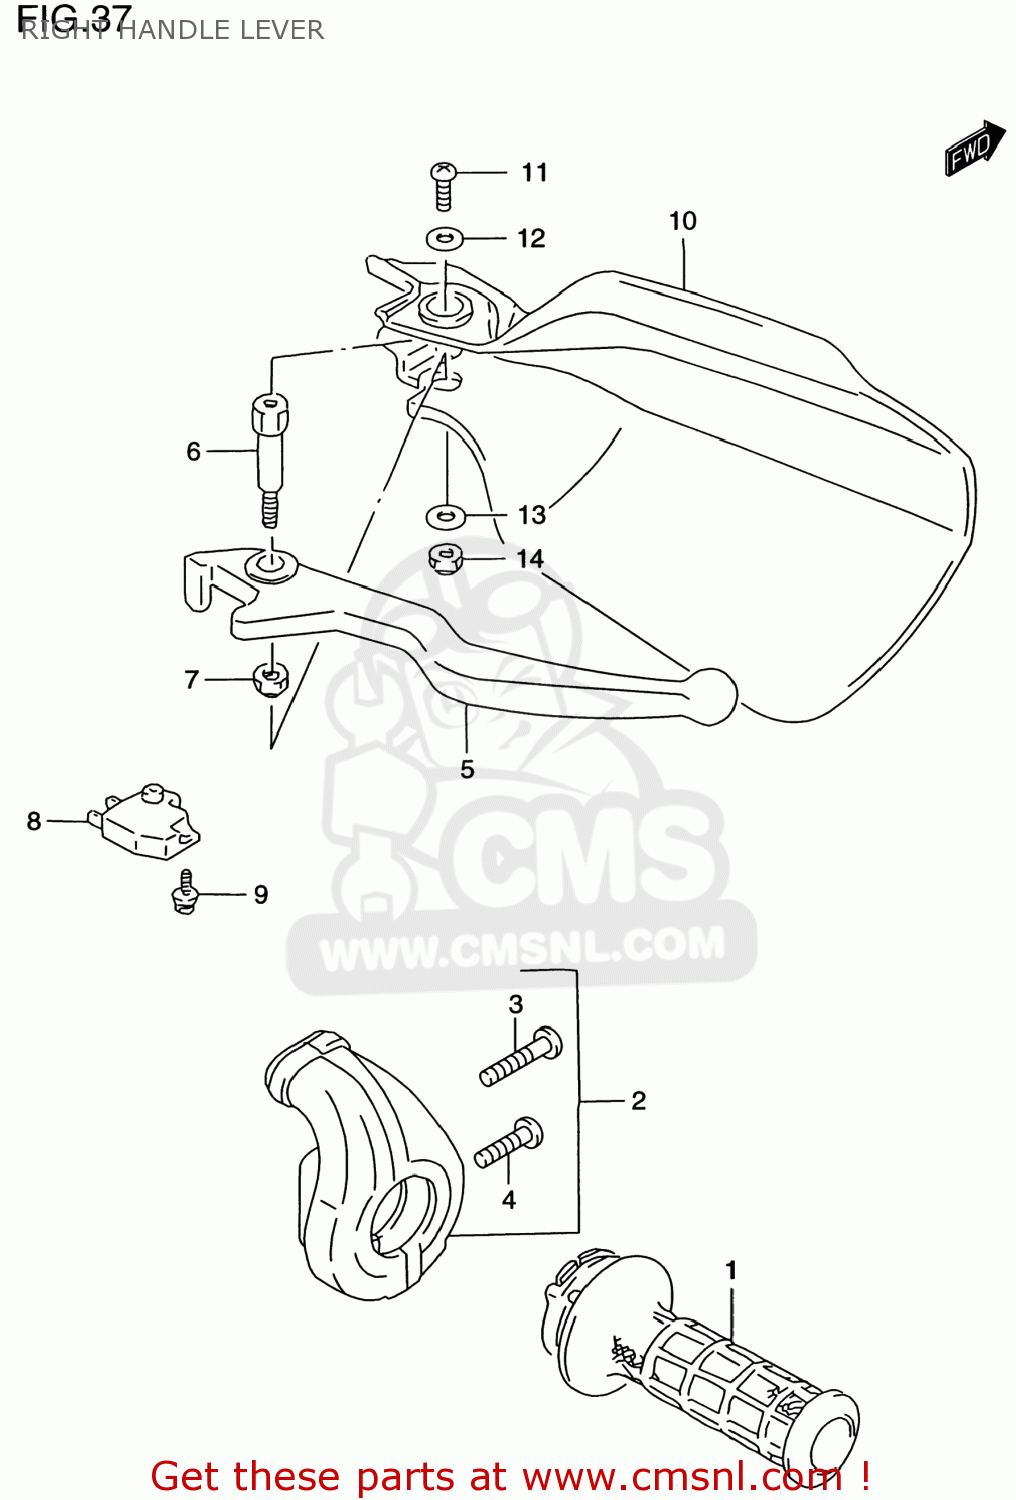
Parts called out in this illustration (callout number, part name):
1	GRIP,THROTTLE
2	CASE ASSY,THROTTLE
3	SCREW(5X25)
4	SCREW
5	LEVER,BRAKE
6	BOLT,BRAKE LEVER PIVOT
7	NUT
8	SWITCH ASSEMBLY,STOP
9	SCREW
10	COVER,KNUCKLE,RIGHT
11	SCREW
12	WASHER(5.5X16X1.2)
13	WASHER(6.5X16X1.6)
14	NUT 6MM
